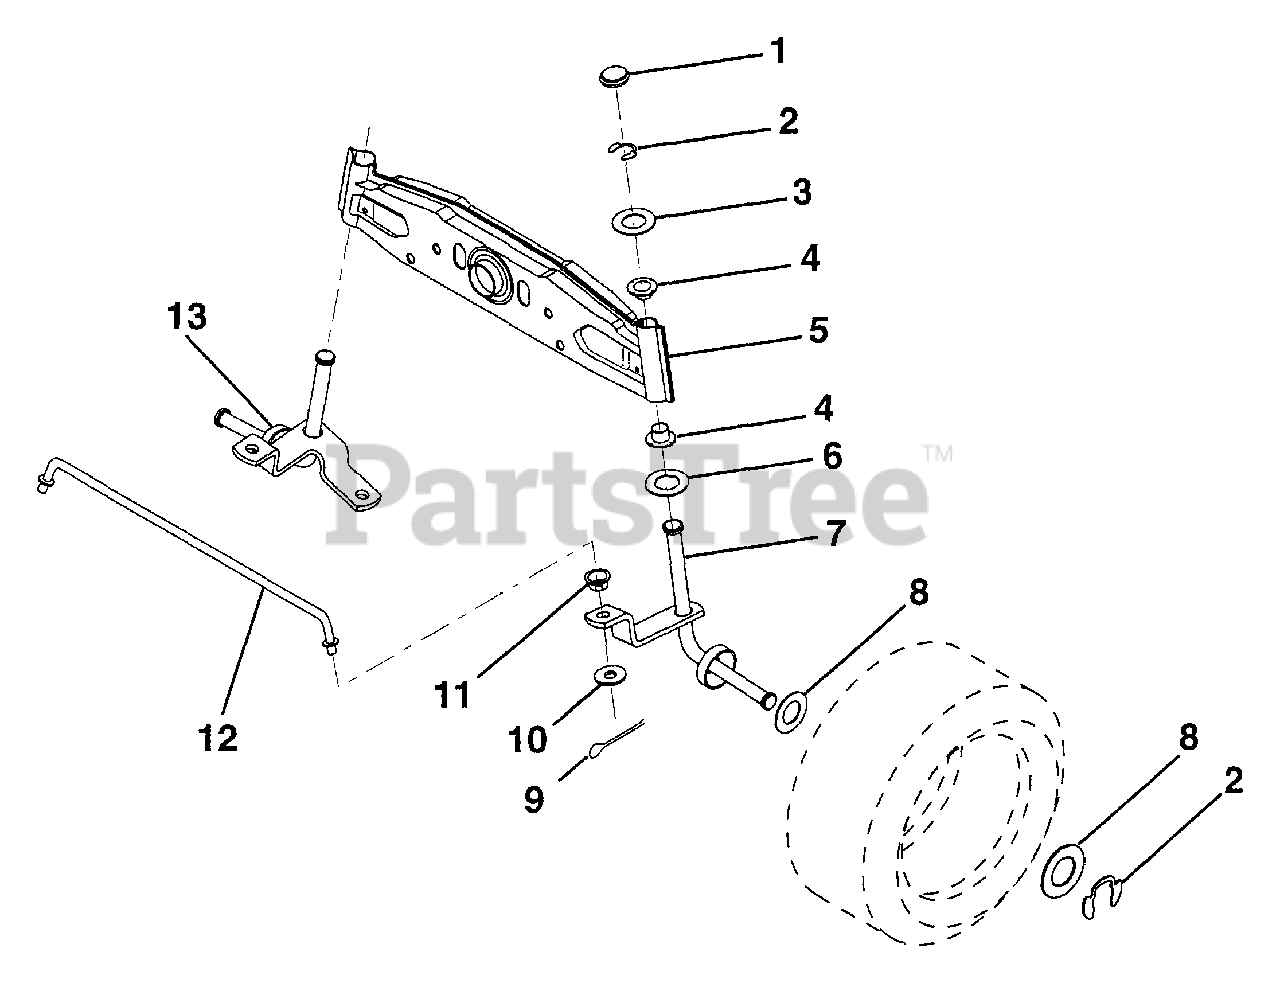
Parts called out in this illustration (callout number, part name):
1	Cap, Spindle
2	Ring, Clip
3	Washer 25/32 x 1-5/8 x 16 Ga.
5	Axle, Front
6	Bearing, Thrust
7	Spindle Assembly, R.H.
8	Washer 25/32 x 1-1/4 x 16 Ga.
9	Pin, Cotter 1/8 x 3/4
10	Washer 13/32 x 13/16 x 16 Ga.
13	Spindle Assembly, L.H.
